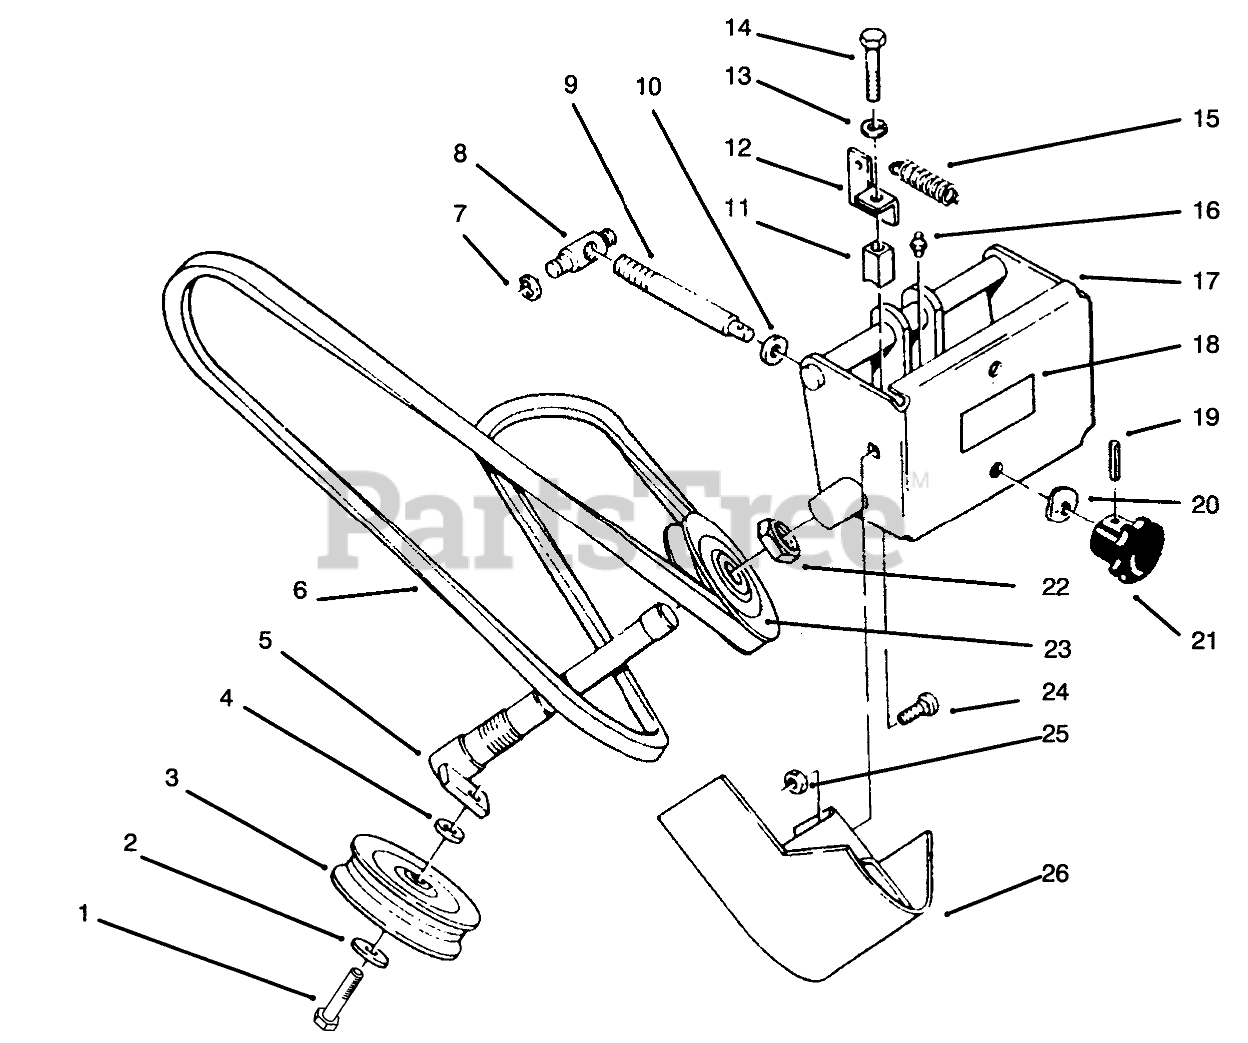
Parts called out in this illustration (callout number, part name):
1	SCREW-HH
2	WASHER-FLAT
3	PULLEY-FLAT IDLER
4	SPACER
5	ASS'Y-IDLER ARM
6	BELT-103" A SECTION
7	RING-RETAINING
8	TRUNNION-DOUBLE
9	ROD ADJ
10	WASHER-FLAT
11	BLOCK-GUIDE
12	Bracket
13	WASHER-LOCK
14	SCREW-HH
15	SPRING-BRAKE
16	FITTING-GREASE
17	Front Idler Support
18	DECAL-ATTACH A-MATIC
19	PIN-ROLL
20	WASHER-SPRING
21	KNOB-ADJUSTMENT
22	NUT-JAM
23	PULLEY-IDLER
24	BOLT-CARR
25	NUT-LOCK, NI
26	Cover
